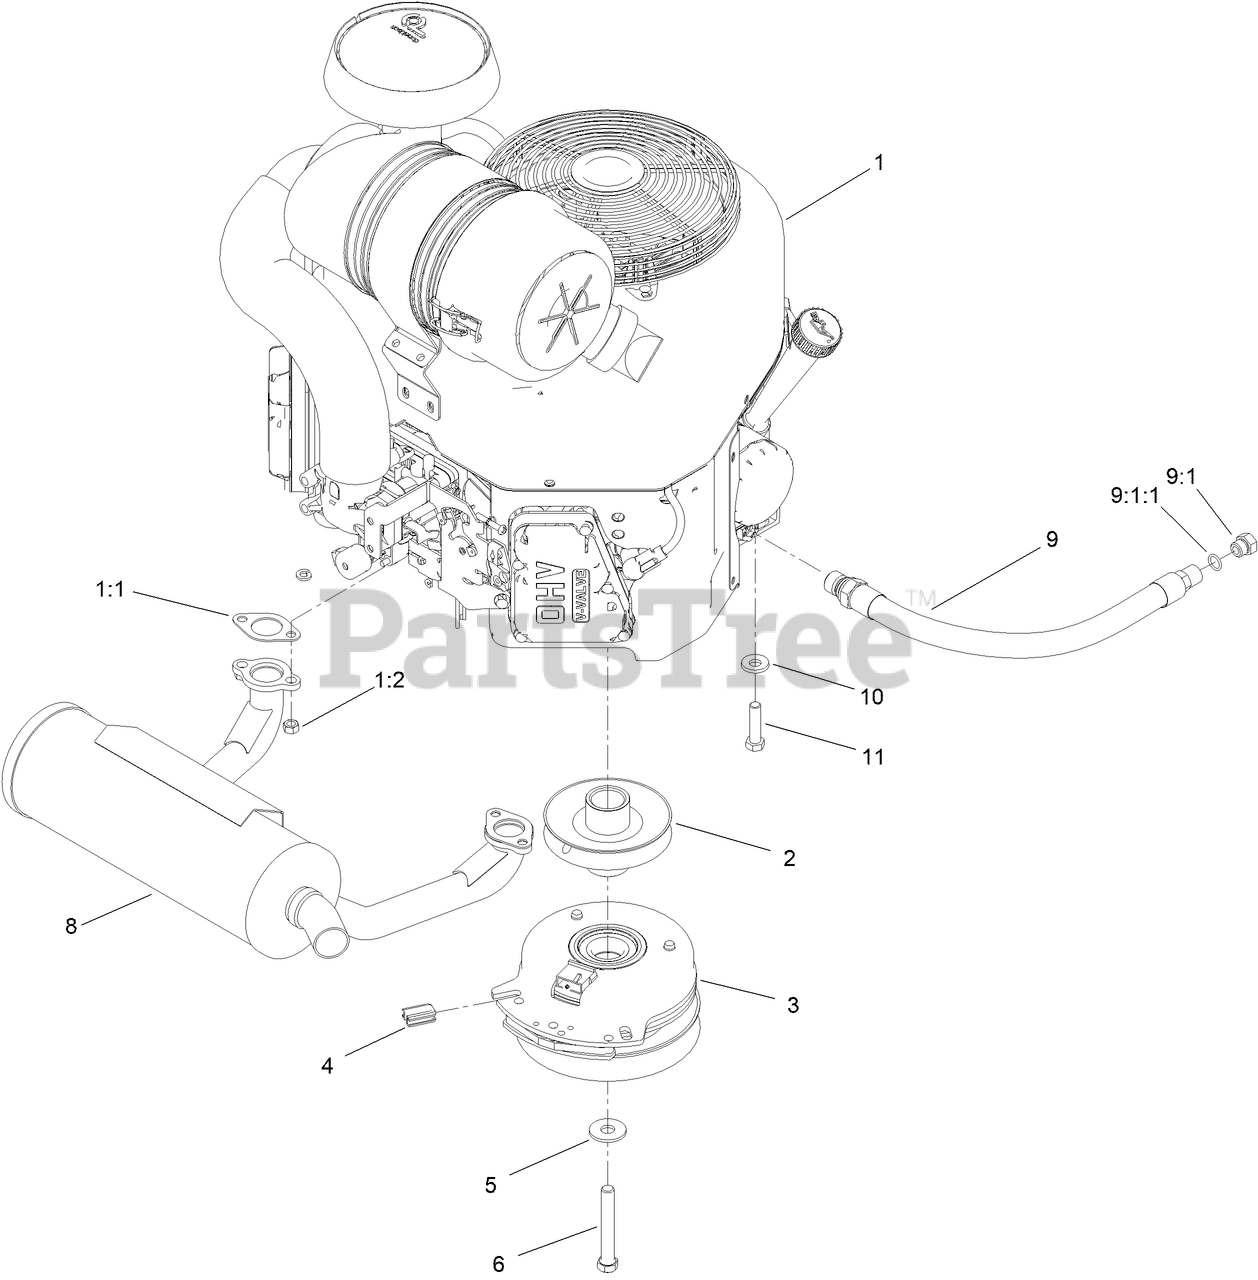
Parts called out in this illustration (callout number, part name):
1:1	GASKET-EXHAUST
2	PULLEY
3	CLUTCH 5.695, 125FTLB, 1.125
4	ISOLATOR-CLUTCH
5	WASHER-HARDENED
6	SCREW-HH W/LOCTITE
8	MUFFLER,HORIZONTAL
9	Asm-Oil Drain Hose W/Plug
9:1	PLUG-HH
9:1:1	O-RING
10	WASHER-BELLEVILLE
11	SCREW-HH
